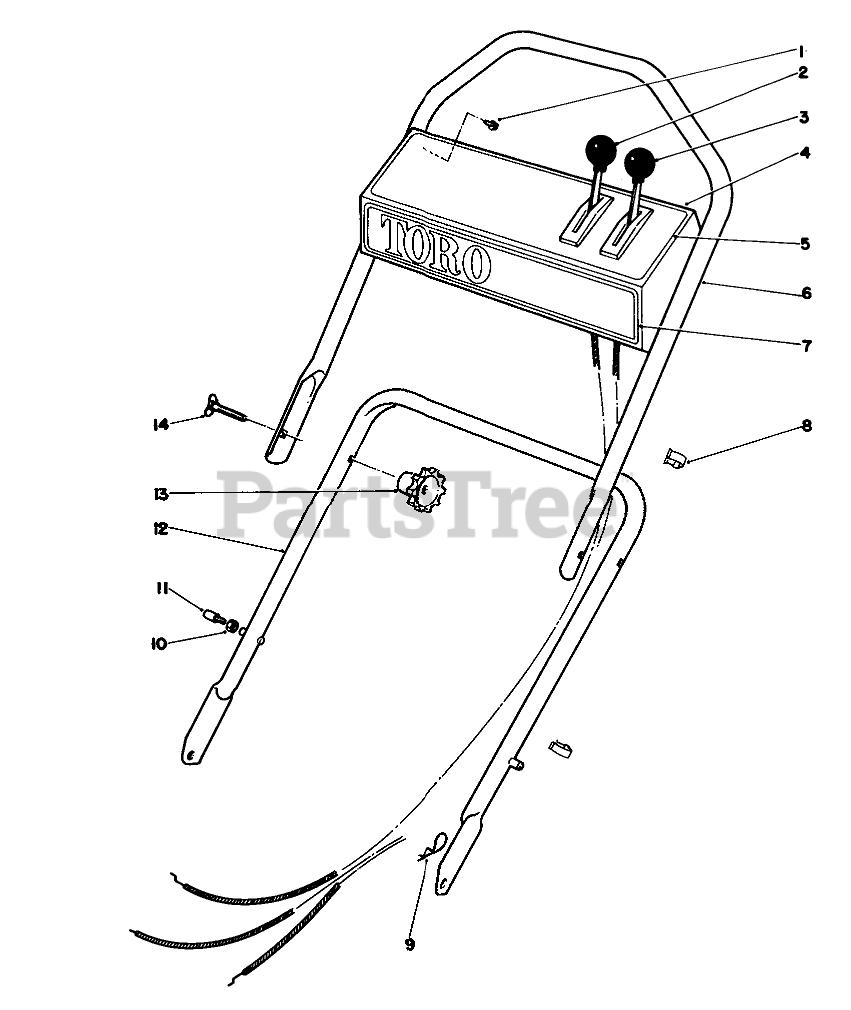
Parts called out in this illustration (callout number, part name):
1	SCREW-HWHTF
2	SERVICE TRACT. CONTROL
3	SERVICE THROTTLE CONTRO
4	Panel-Control (Incl. Ref. #5)
5	DECAL
6	Handle-Upper
7	Decal-Toro
8	BOWDEN CLIP
9	PIN-COTTER, HAIR
10	NUT-LOCK, NI
11	HANDLE PIN
12	LOWER HANDLE ASM
14	5/16-18 X 2 HNDLE SCREW
